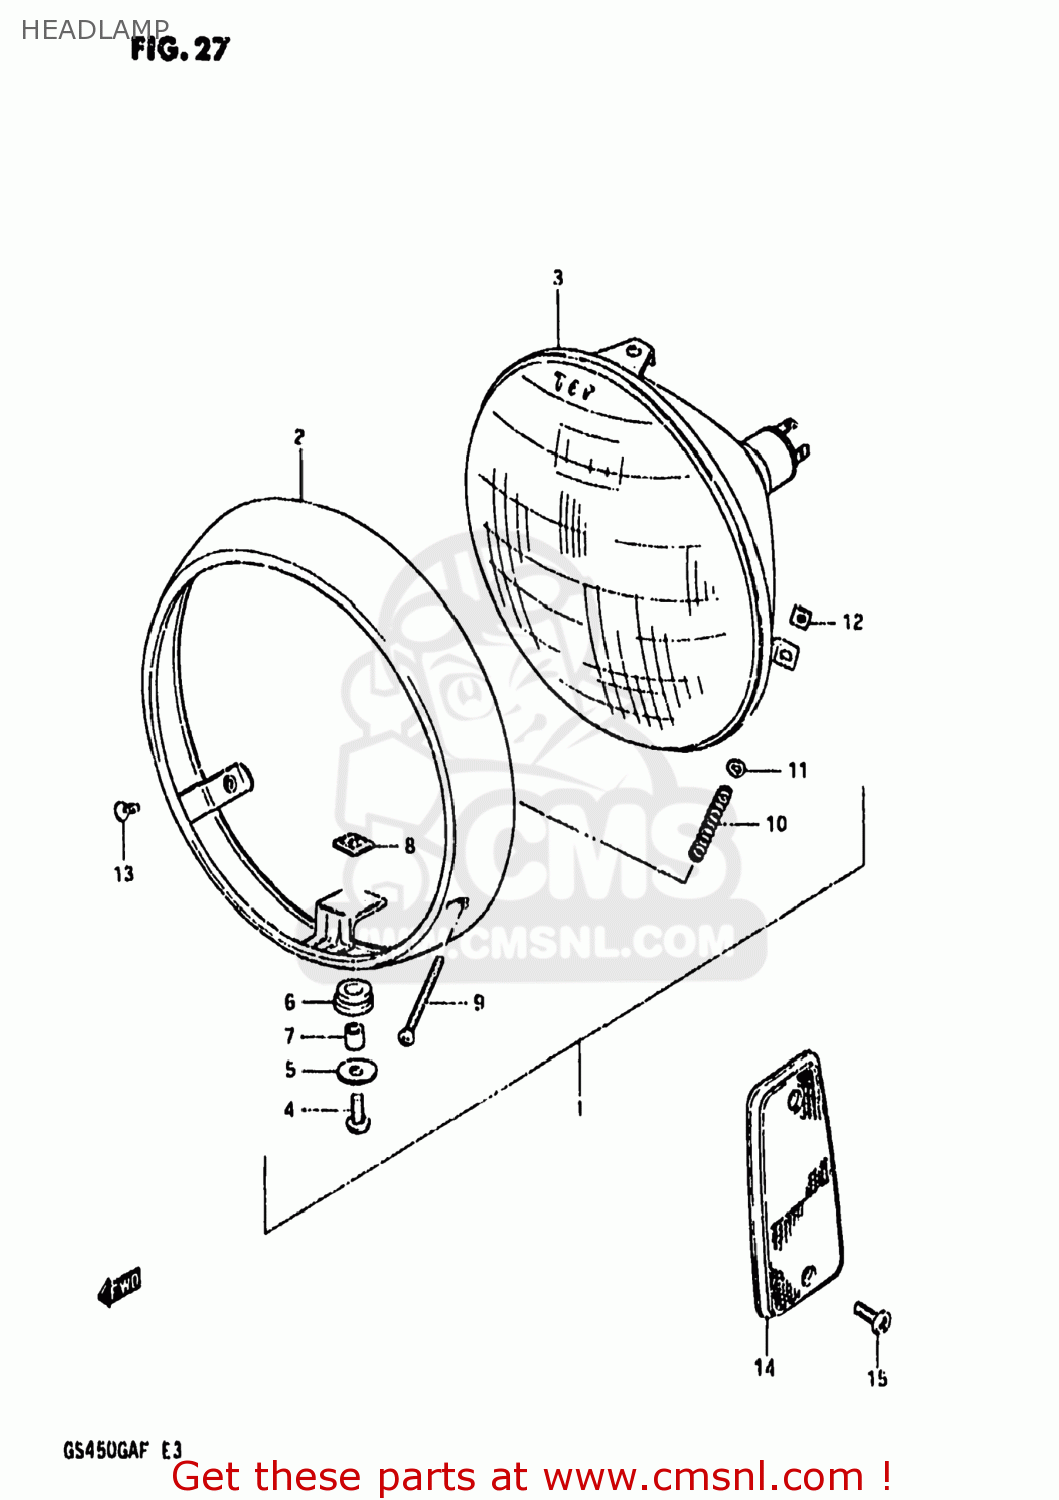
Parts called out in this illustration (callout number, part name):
1	LAMP ASSEMBLY,HEAD
2	RIM
3	LAMP UNIT
4	SCREW
5	WASHER
6	CUSHION
7	SPACER
8	NUT
9	SCREW
10	SPRING
11	WASHER
12	NUT,HEADLAMP ADJUSTER
13	SCREW(5X12)
14	REFLECTOR,REFLEX
15	SCREW 4X10
